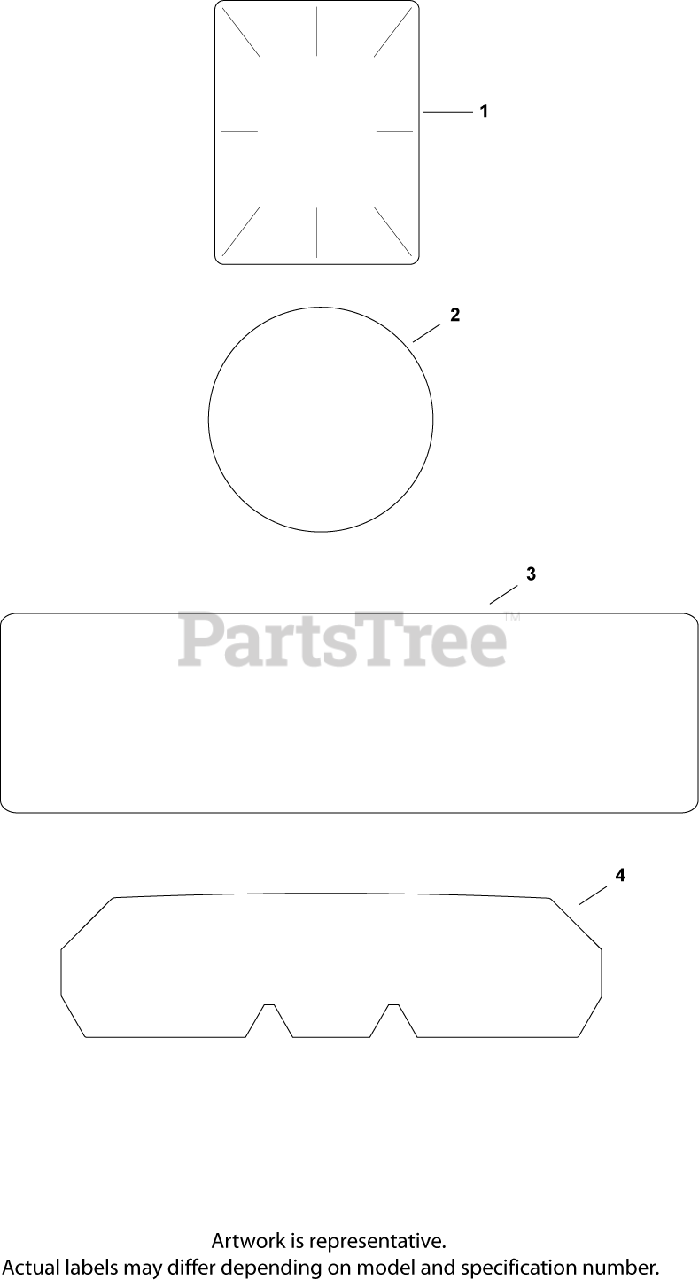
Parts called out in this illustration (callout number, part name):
1	DECAL, CLEAR LAMINATE USE 25 113 70-S
2	DECAL, GRASS SCREEN USE 24 113 499-S
3	DECAL, 23 HP - DISCONTINUED
4	DECAL, HEAT REFLECTIVE
